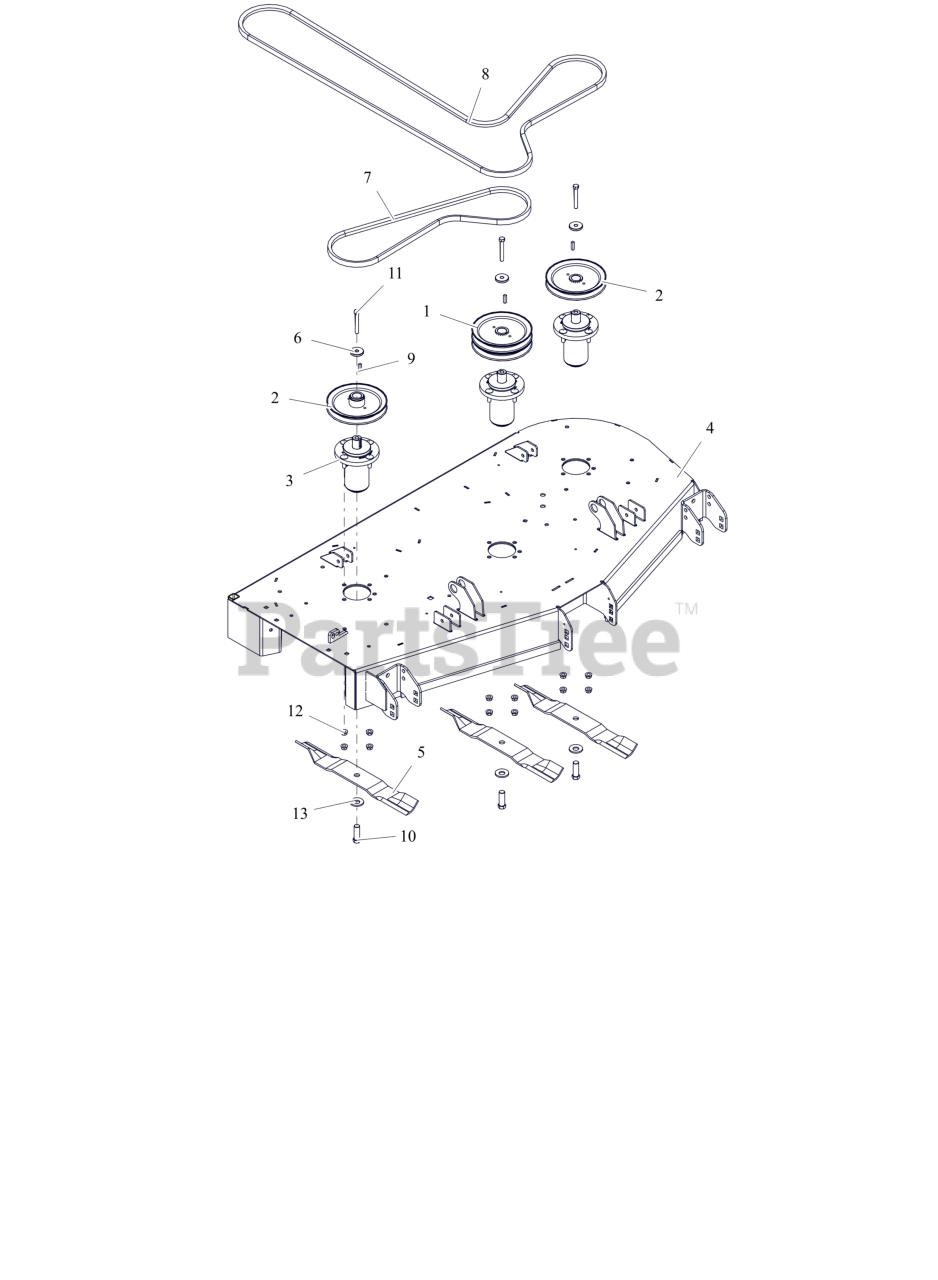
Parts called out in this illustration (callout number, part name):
1	PULLEY, DOUBLE-1"ID X 6.75"OD
2	PULLEY, V-1" ID X 6.75" OD
3	ASM, MAINT FREE ALUM SPINDLE
4	WLDMT, 52 SIDE DISCH DECK CE (ORANGE)
5	BLADE, 18"
6	RETAINER, SHEAVE
7	V-BELT, B-COGGED
8	V-BELT, HB SECTION
9	KEY, SQ .25X.25X1.00 RC 40-50
10	BLT, HEX .62-18X1.75 G8 ZCC
11	BLT, HEX .38-16X2.75 G8 ZCC
12	NUT-LK-CTR-FLG .375-16 GF ZCC
13	WSHR-BLVL .669X1.535X.138
